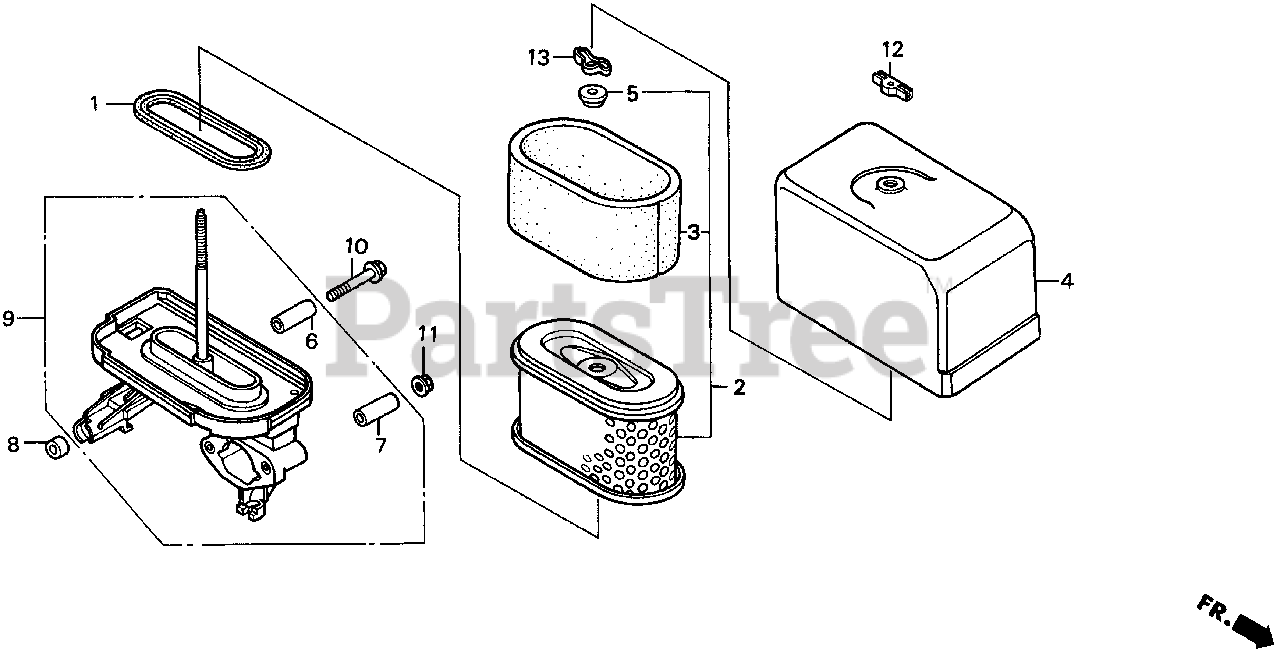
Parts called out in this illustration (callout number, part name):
1	GASKET, ELBOW
2	ELEMENT, AIR CLEANER (Honda Code 3133808). (METAL BASE)
2	ELEMENT, AIR CLEANER (METAL BASE)
3	FILTER (OUTER)
4	COVER, AIR CLEANER (DUAL)
5	GROMMET, AIR CLEANER
6	COLLAR, AIR CLEANER Use up to Engine SN 1786084.
7	COLLAR, AIR CLEANER
8	SPACER, AIR CLEANER ELBOW
9	ELBOW, AIR CLEANER
10	BOLT, FLANGE (6X45)
11	NUT, CAP (6MM)
11	NUT, FLANGE (6MM)
12	WINGNUT (6MM)
13	WINGNUT, TOOL BOX SETTING
